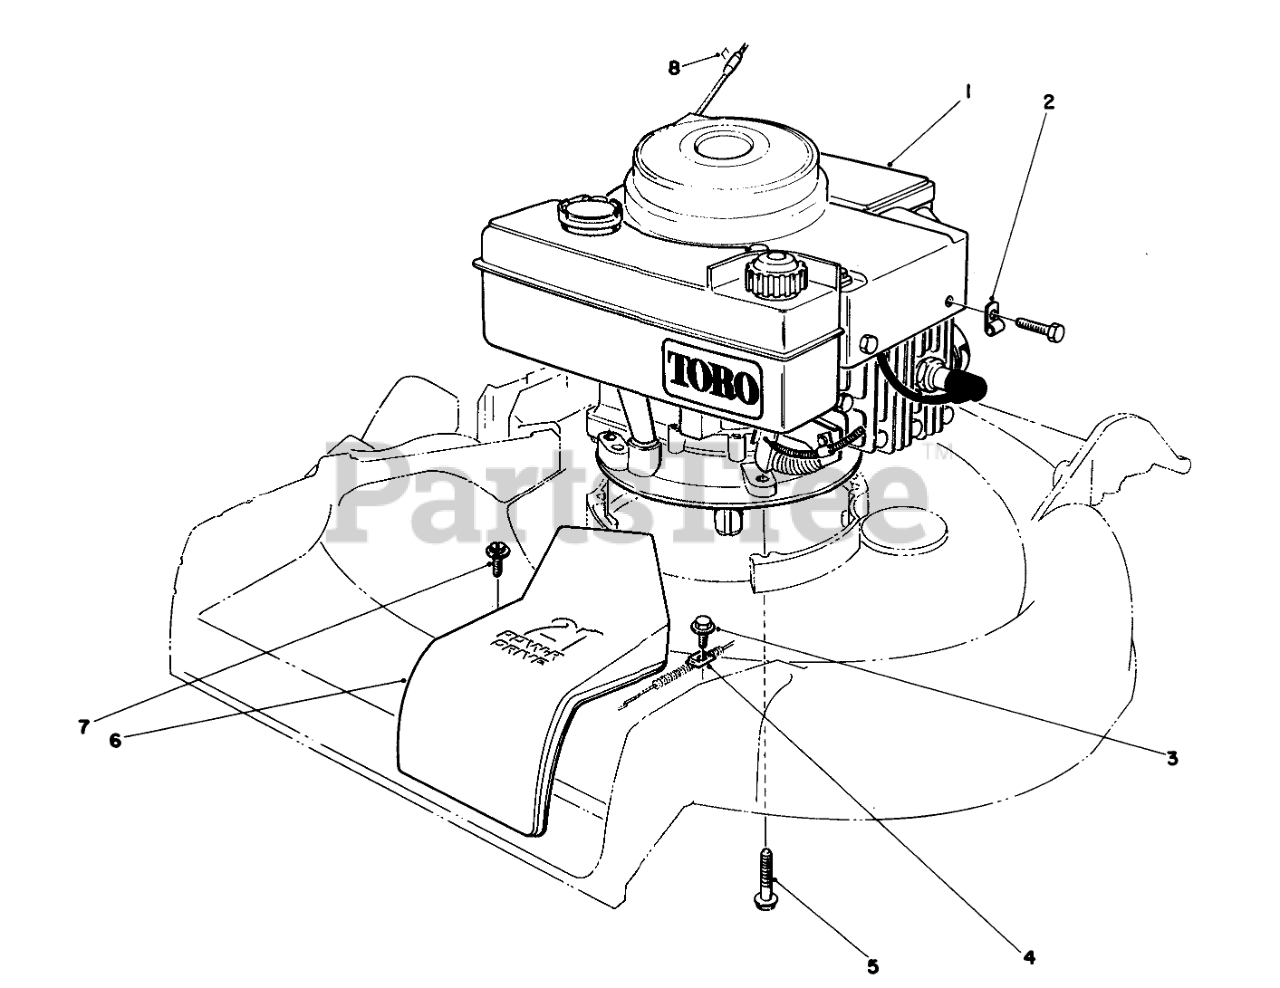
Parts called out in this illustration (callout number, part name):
2	CLAMP
3	SCREW-HWHTF
4	CLAMP-CABLE
5	3/8-16 X 2-3/4 CAPSCR
6	BELT COVER 21" S D
7	SCREW
8	Staple
